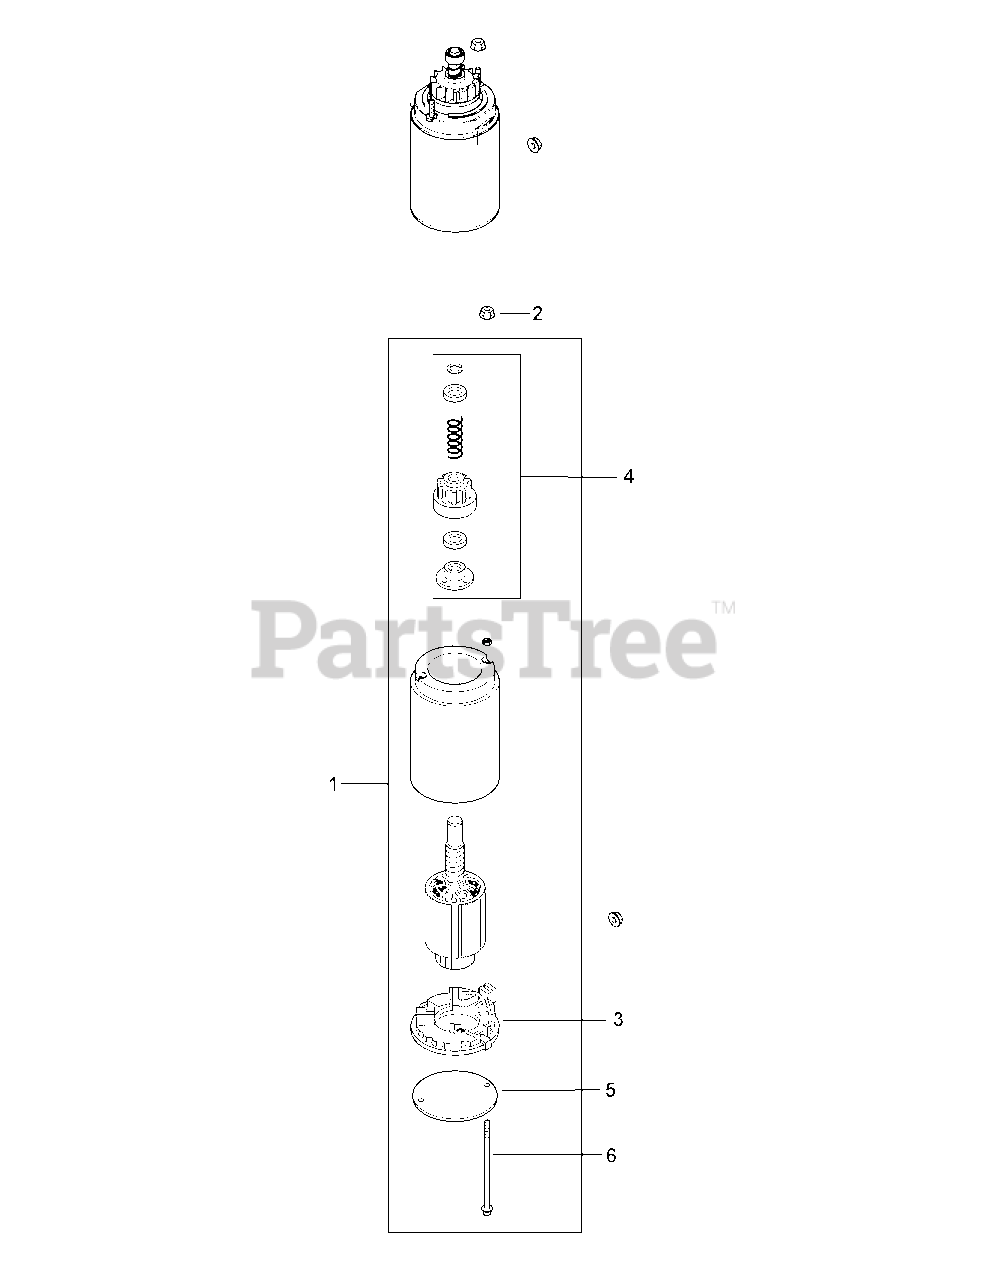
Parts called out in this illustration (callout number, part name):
1	Starter Assembly
2	Free Spinning Flange Nut, #10-24
4	Drive Kit (J.E.)
5	Drive End Cap (J.E.)
